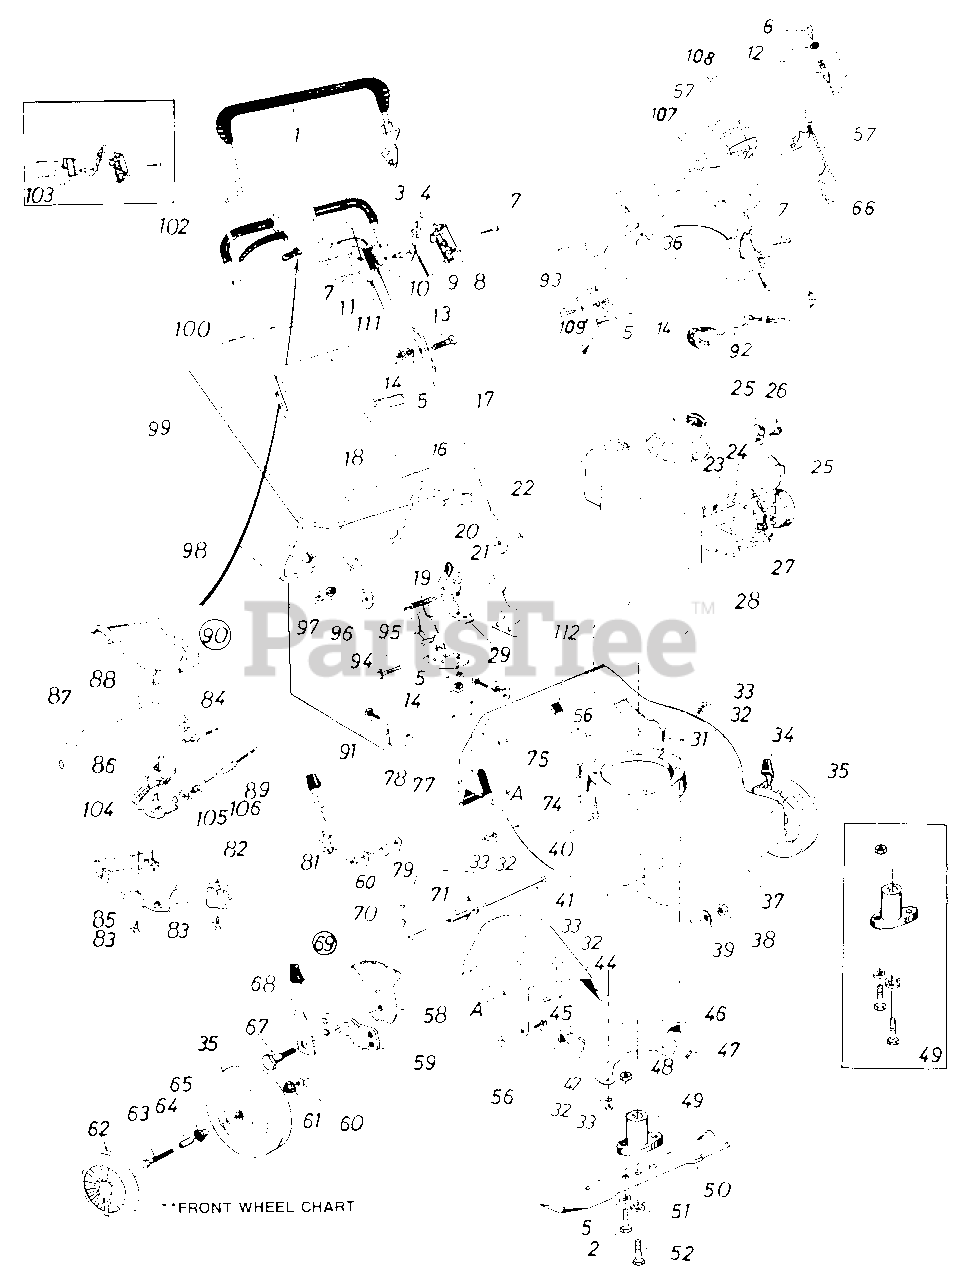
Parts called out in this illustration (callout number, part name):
1	L.H. Bail Ass'y.
2	Hex Bolt 5/16-24 x 1.00" Lg. (Grade 5)
3	Control Disc Pin
4	Throttle Control Lever
5	L-Wash. 5/16" I.D.*
6	Ignition Key
7	Truss Mach. Hi-B Tap Scr. #12 x 1.50" Lg.
8	Control Panel Half
9	Throttle Control Wire 58"
10	Control Label
11	Clutch Panel Half
12	Ignition Switch
13	Carr. Bolt 5/16-18 x 1.75"
14	Hex Nut 5/16-18 Thd.*
16	Cable Tie
17	Lower Handle
20	Shld. Bolt .437" Dia. x .162
21	Handle Brkt. Ass'y. L.H.
22	Hairpin Cotter 5/16" Dia.
23	Casing Clamp
24	Hex B-Tap Scr. #10 x .62"
25	Cable Clip
26	Hex B-Tap Scr. #10 x .38"
27	Spark Plug Insulator
28	Engine
29	Lock Lever w/Knob
31	Hex TT-Tap Scr. 1/4-20 x .5" Lg.
32	L-Wash. '/4" I.D.*
33	Hex Nut 1/4-20 Thd.*
34	Height Adj. Ass'y. L.H.
35	** Front Wheel Ass'y. Comp.
36	Lower Battery Tray
39	Bell-Wash. .39" I.D. x 1.38"
40	Hex Wash. Hd. TT-Tap Scr. 3/8-16 x 1.0" Lg.
44	Rear Chute R.H.
45	Shld. Bolt.500" Dia.
46	Rear Baffle L.H.
47	Carr. Bolt 1/4-20 x .50" Lg.*
48	Hex Nut 5/16-24 Thd.*
49	Blade Adapter Kit
50	22" Blade
51	L-Wash. 3/8" I.D. H.D.
52	Hex Bolt 3/8-24 x 2.25" Lg. (Grade 5)
56	Hex Sems Nut '/4-20 Thd.
57	Wire Harness
58	Height Adj. Plate
59	Wheel Pivot Bar
60	Bell-Wash. .40" I.D. x .88"
61	Flg. Ball Brg. 318" I.D.
62	Plastic Hub Cap
63	Hex Bn lt 3/8-16 x 1.75" Lg.
64	Spacer.375" I.D.
65	Flg. Ball Brg. 1/2" I.D.
66	Plug
67	Shld. Bolt .50" Dia. x .430
68	Spring Lever Ass'y. w/Knob
69	Height Adj. Ass'y. R.H.
70	Chute Door
71	Torsion Spring
74	Hex Bolt 1/4-20 x .88" Lg.
75	Fl-Wash. .285" I.D. x 1.25"
78	Grass Catcher Hitch Brkt.
79	Bell-Wash. .40" I.D. x 1.13
81	Hex Jam Nut 3/8-16 Thd.
82	Cable Mounting Cap
83	Flat "C"-Sunk Hd. Tap Scr. #10 x .75" Lg.
84	S.P. Cable x 53" Lg.
85	3-Sp. S.P. Control Lower Cover
86	Shimano 3-Sp. Shift Lever
87	Control Lever
88	3-Sp. S.P. Control Upper Cover
89	Shimano 3-Sp. Solid Shift Cable
90	Clutch Control Hsg. Comp.
91	Carr. Bolt 1/4-20 x .75" Lg.*
92	Battery Charger
93	Carr. Bolt 5/16-18 x 1.38"
94	Hex Bolt 1/4-28 x .75" Lg.
95	Handle Brkt. Ass'y. R.H.
96	Push Nut 3/8" Rod
97	Plastic Roller
98	Grass Bag
99	Catcher Upper Frame
100	Upper Handle
102	Grip
103	Control Housing Comp.
104	Shimano 3-Sp. Shift Lever Brkt.
105	Shimano 3-Sp. Cable Spring Brkt.
106	Shimano 3-Sp. Cabe Mounting Spring
107	Battery Pack
108	Battery Tray
109	Truss Mach. Hi-Riser Tap Scr. 1" Lg.
111	Clutch Control Cable 45"
8367-000-7	Hardware Pack
